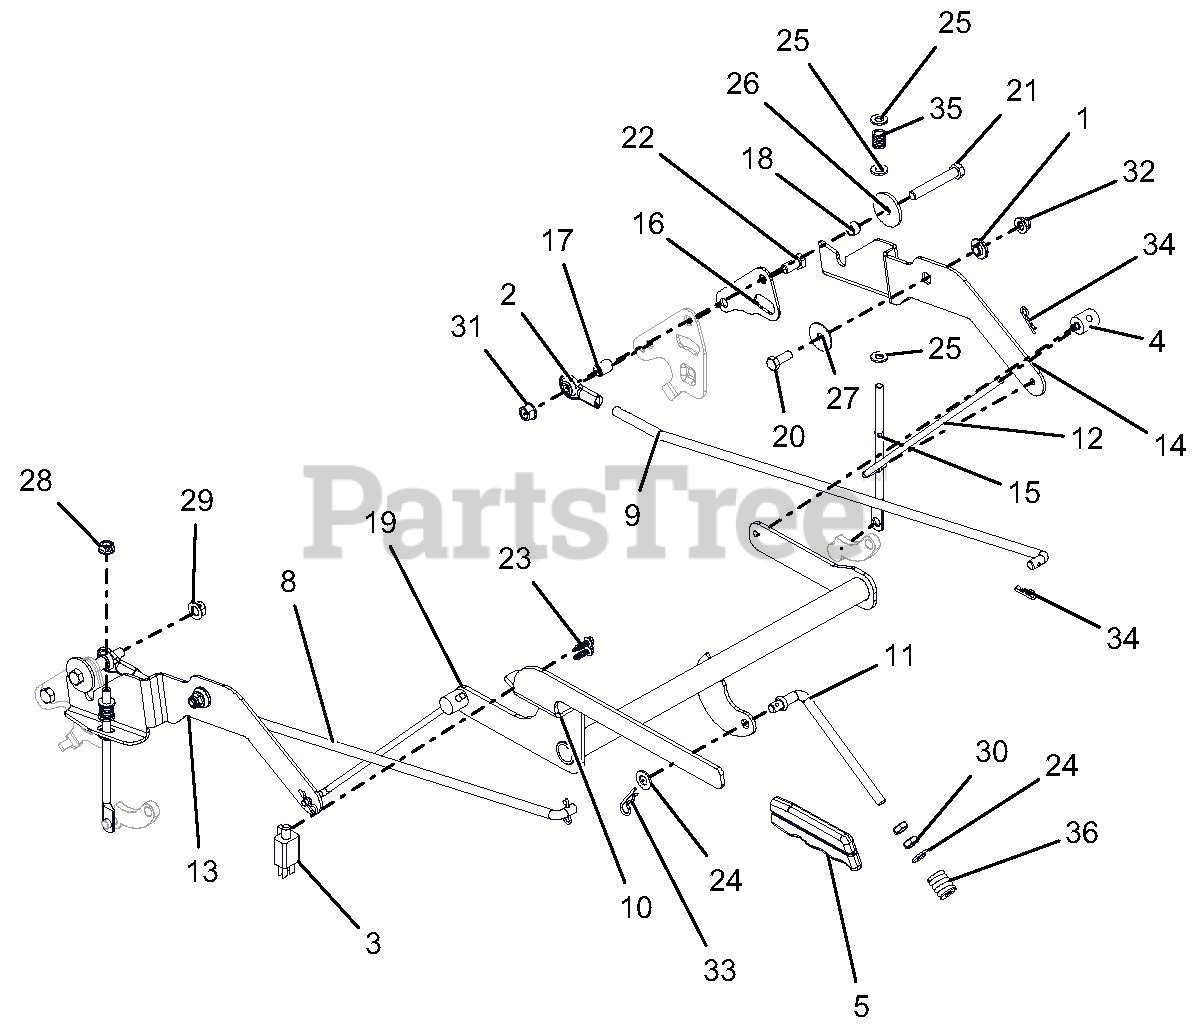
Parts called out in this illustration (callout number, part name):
1	BSHG, FLG .325X.499X.26X.88
2	ROD END, .38 RH
3	SWITCH- DOUBLE POLE N.O./N.O.
4	TRUNION, 1/4-20
5	GRIP, PARKING BRAKE
8	LINK, RH STEERING
9	ROD, STEERING LINKAGE LH
10	WLDMT, BRAKE LEVER
11	LINK, OVER CENTER BRAKE
12	LINK, BRAKE ARM
13	INTERLOCK, RH BRAKE LINK
14	INTERLOCK, LH BRAKE LINK
15	LINK, BRAKE COG
16	PLATE, TRANSAXLE ADAPTOR
17	SPCR, .385X.500X.652
18	SPCR, .385X.500X.350
19	E-RING, .250 X .025
20	BLT-HEX .31-18X.875 GR5 YWZC
21	BLT-HEX .38-16X2.50 GR5 YWZC
22	BLT-HEX .38-16X.75 GR5 YWZC
23	SCR-TAP #12X.75 BOSS INDHXHD
24	WSHR-FL-STL.406X.812X.065 YWZ
25	WSHR-FL-STL.344X.688X.065YWZC
26	WSHR-FL-STL .380X1.50X.125 YWZC
27	WSHR-FL-STL .347X1.254X.048 YWZC
28	NUT, LK-CTR-FLG .31-18 YWZC
29	NUT, LK-CTR-FLG .38-16 YWZC
30	NUT, JAM .375-16 YWZC
31	NUT, LK-TOP-FLG .38-16 YWZC
32	NUT-LK-NYL-FLG .31-18 YWZC
33	PIN-COTR .09 X 1.50 YWZC
34	PIN, HAIR INT .08X.18X1.18 YWZC
35	SPRG, COMPRESSION
36	SPRG, COMPRESSION
